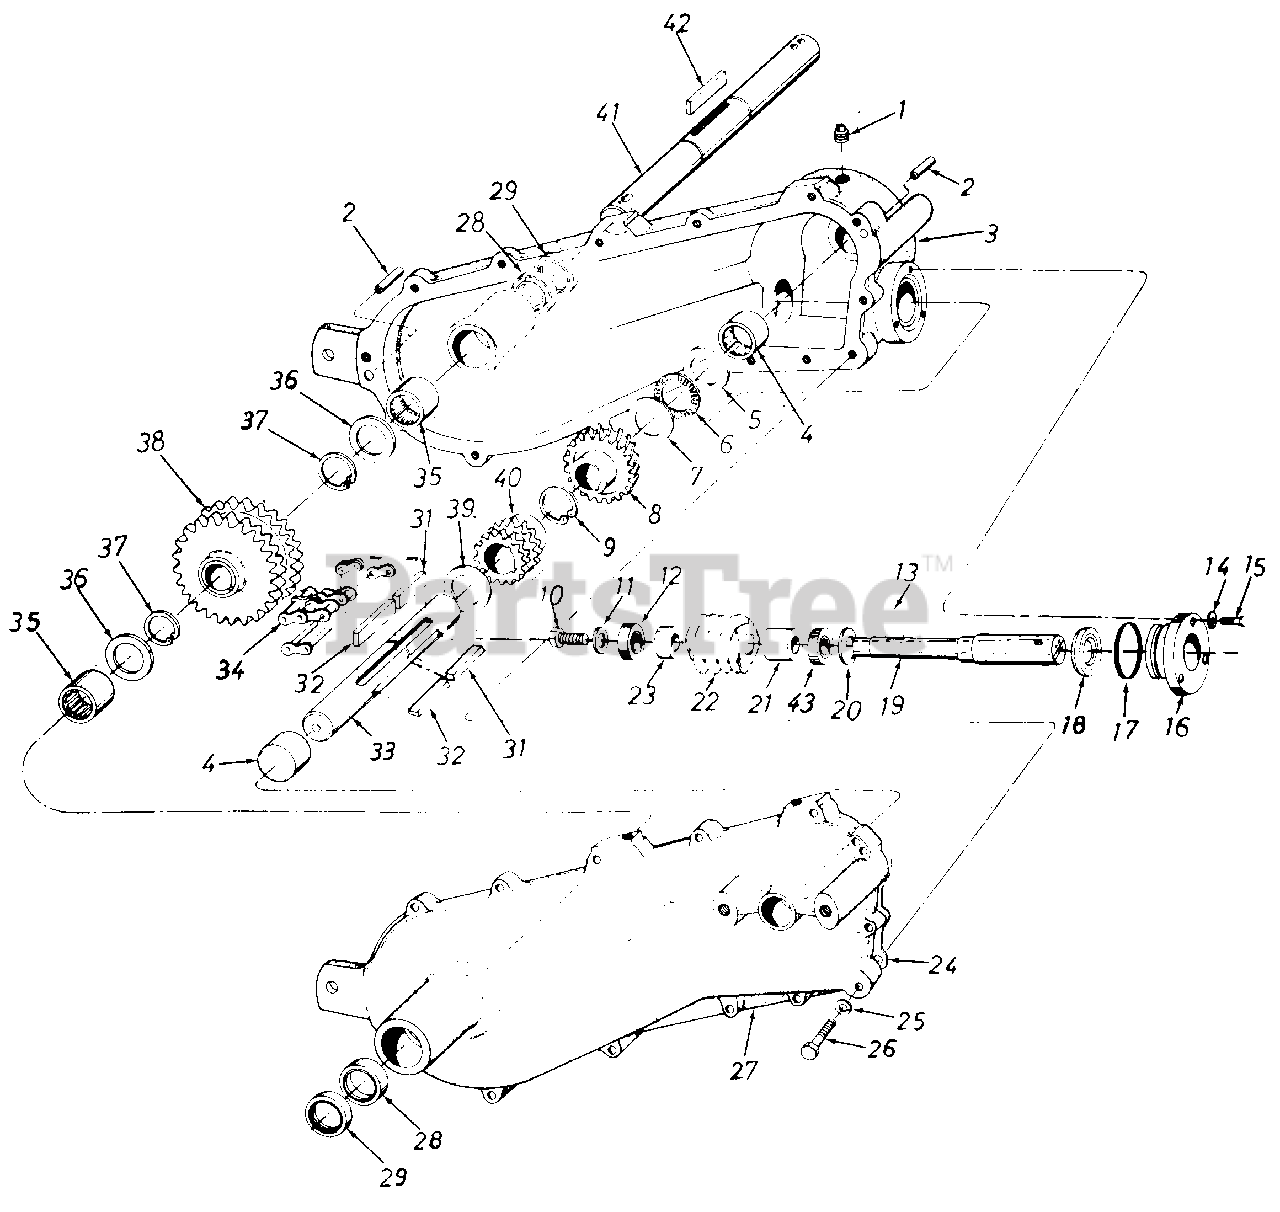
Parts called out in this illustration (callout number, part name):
1	Sq. Hd. Pipe Plug with Vent
2	Spring Pin Spiral 5/16" Dia. x 1.75" Lg.
3	Gear Case-L.H. Half
4	Needle Bearing
5	Thrust Race 1.25" I.D. x .126 Thk.
6	Thrust Bearing 1.25" I.D. x 1.977 O.D.
7	Thrust Race 1.25" I.D. x .303 Thk.
8	Worm Wheel
9	Snap Ring-for 1.25" Dia. Shaft
10	Hex Lock Scr. 5/16-24 x .75" Lg.
11	Belleville Wash. 5/16" Dia.
12	Ball Bearing .669 I.D. x 1.85O.D. x .5
13	#9 Hi-Pro-Key 3/16" x 3/4" Dia.
14	L.-Wash. 1/4" Scr.*
15	Hex Scr. 1/4-20 x .88" Lg.*
16	End Cap
17	"O"-Ring
18	Oil Seal .875" I.D. x 1.503 O.D.
19	Worm Input Shaft
20	Fl.-Wash. .793 I.D. x 1.240 O.D.
21	Clutch Idler Bushing
22	Worm Gear
23	Spacer
24	Gasket
25	L.-Wash. 5/16" Scr.*
26	Hex Scr. 5/16-18 x 1.75" Lg.*
27	Gear Case-R.H. Half
28	Oil Seal 1.25" I.D. x 2.004" O.D.
29	Oil Seal 1.25" I.D. x 2.004" O.D.
31	Sq. Key 5/16 x 1.25" Lg.*
32	Sq. Key 5/16 x 1.75" Lg.*
33	Worm Gear Shaft
34	Chain w/master link #60 x 39
35	Needle Brg. 1.25" I.D. x 1.927" O.D.
36	Thrust Bearing
37	Tru arc Snap Ring
38	Sprocket-25 Teeth
39	Thrust Bearing
40	Sprocket 13 Tooth
41	Tine Shaft
42	Sq. Key 5/16" x 2.0" Lg.*
43	Ball Bearing .787 I.D. x 2.048 O.D. x .59
